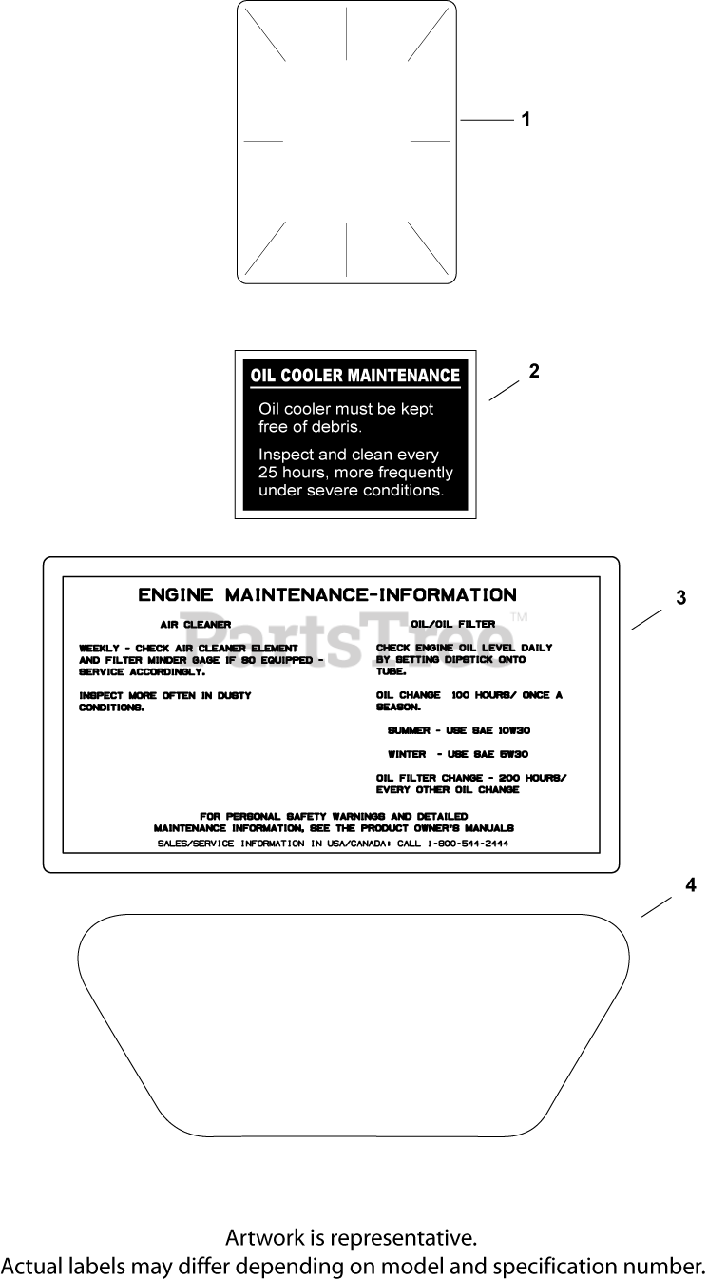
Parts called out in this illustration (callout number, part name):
1	DECAL, CLEAR LAMINATE USE 25 113 70-S
2	DECAL, OIL COOLER - (#DSC)
3	DECAL, AIR CLEANER - (#DSC)
4	DECAL, 27 HP EVERRIDE
